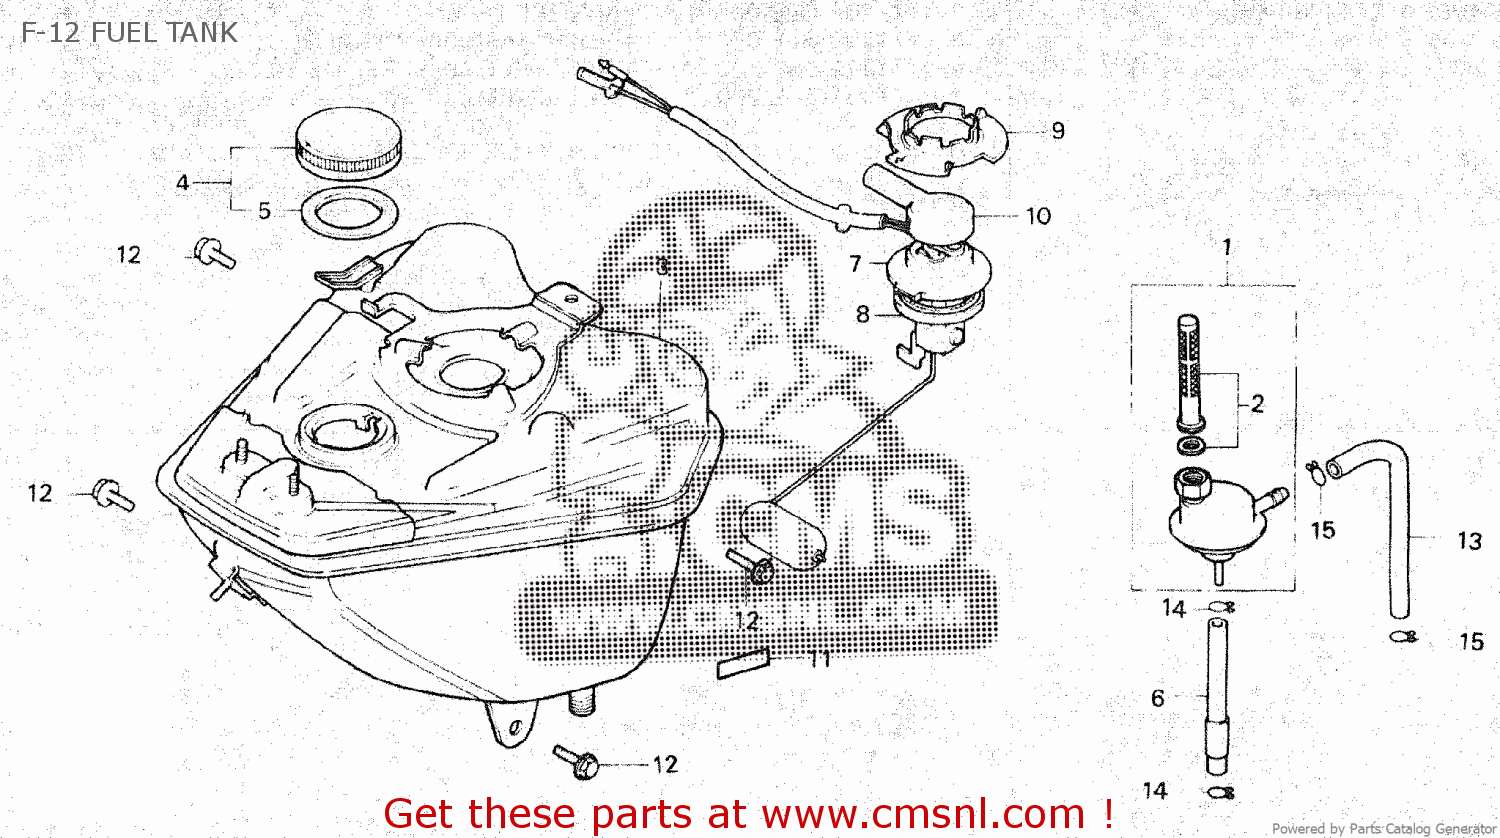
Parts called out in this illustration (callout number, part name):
1	COCK,FUEL AUTO
2	SCREEN SET,F/STR
3	TANK COMP.,FUEL
4	CAP FUEL FILLER
5	PACKING,CAP
6	TUBE,FUEL,3.5X125
7	FUEL UNIT
8	PACKING,BASE
9	RET,FUEL UNIT
10	COV,FUEL UNIT
11	LABEL,FUEL
12	BOLT,FLANGE,6X14
13	TUBE,FUEL 4.5X140
14	CLIP B7,TUBE
